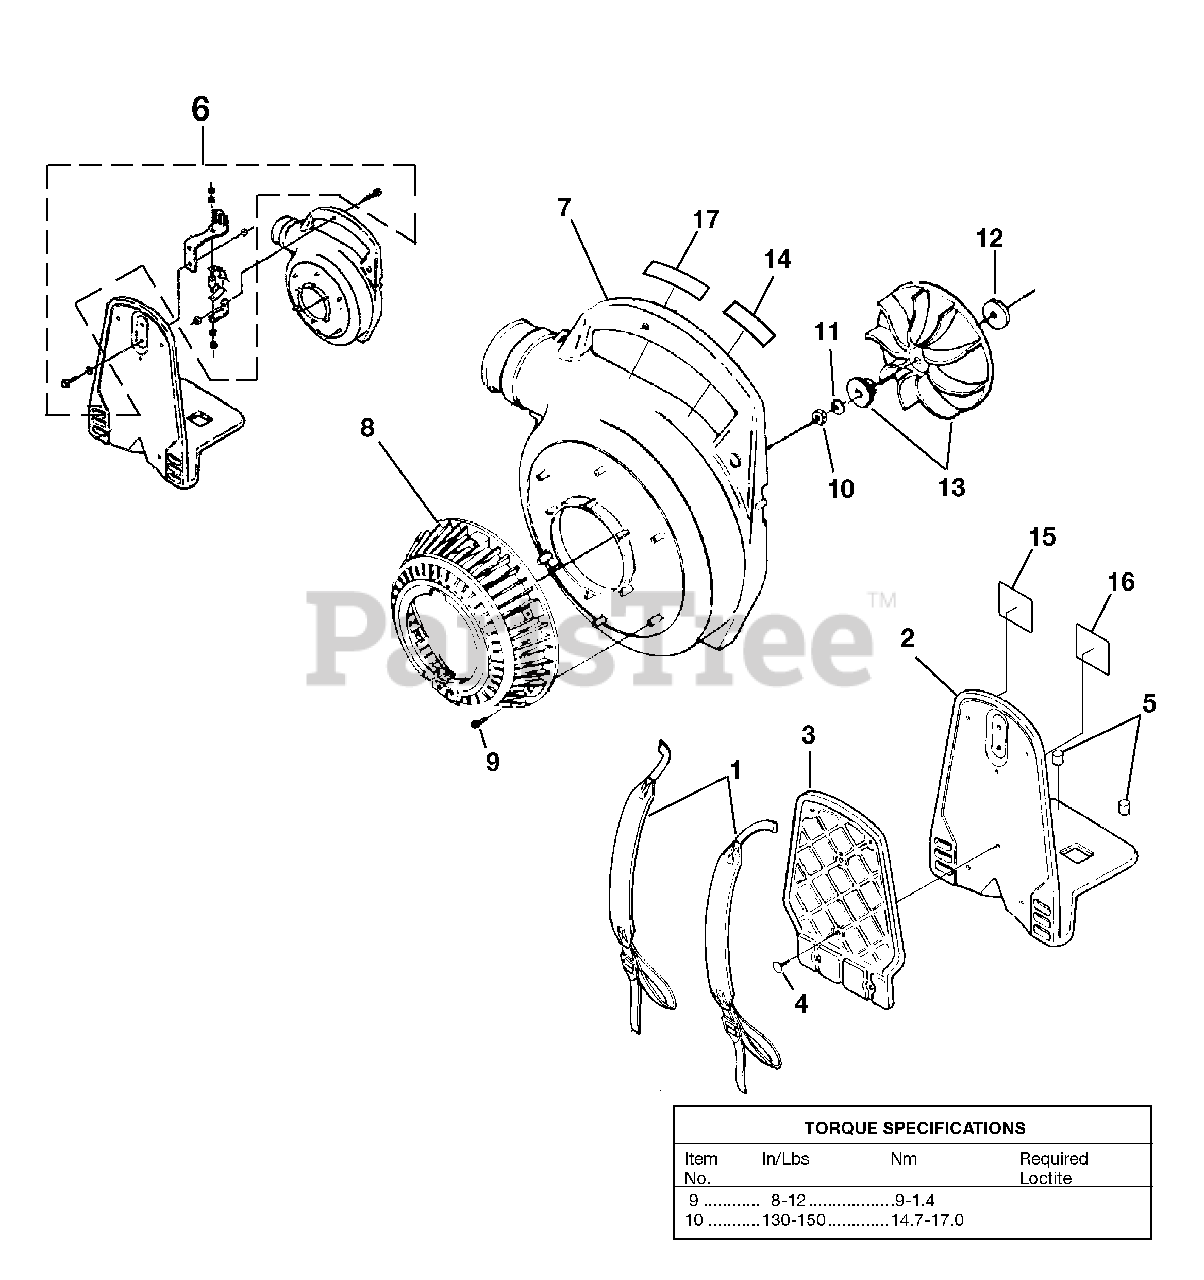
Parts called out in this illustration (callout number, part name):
1	HARNESS-Shoulder
2	FRAME-Blower
3	PAD-Foam
4	CLIP-Push
5	VIBRATION ISOLATOR
6	VIBRATION ISOLATOR KIT
7	VOLUTE HOUSING KIT
8	BLOWER VAC GRILLE KIT
9	SCREW-Thread Form. (#6 X 3/8")
10	NUT-Hex (3/8-24)
11	WASHER-Bellville (3/8")
12	WASHER-Flat
13	BLOWER FAN KIT
14	DECAL-Decible Level 69 d B (A)
15	DECAL-Zip Start
16	DECAL-WARNING
17	LABEL-Backpacker
